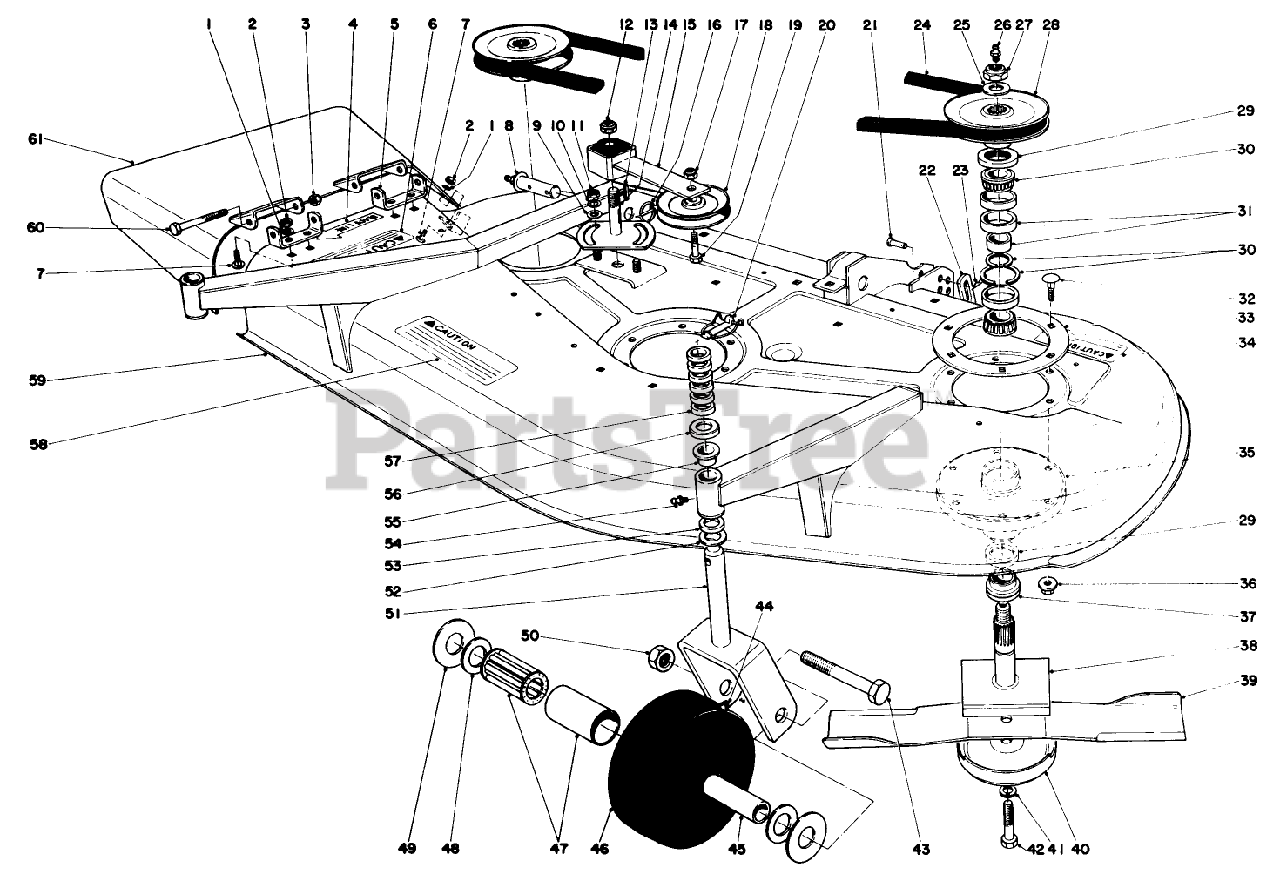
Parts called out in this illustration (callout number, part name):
1	WASHER-LOCK
2	NUT-HEX
3	NUT-LOCK, NI
4	DECAL - BLADE LINE
5	Pivot Bracket Deflector
6	DECAL-CAUTION, DEFLECTOR
7	SCREW-CARR
8	PIVOT PIN WA RO
9	WASHER-FLAT
10	WASHER-LOCK
11	NUT-JAM
12	NUT-LOCK, NI
13	KEY-SQUARE
14	Plate-Idler
15	IDLER ARM ASM
16	PIN-LYNCH
17	NUT-HEX
18	Idler Pulley
19	SCREW-HH
20	PIN-LYNCH
21	PIN-CLEVIS
22	LIFT BRKT LINKAGE R
23	PIN-HAIR
24	V-BELT
25	WASHER
26	FITTING-GREASE
27	NUT-LOCK, NI
28	PULLEY AND HUB ASM
29	SEAL-OIL
30	BEARING ASM
31	SPACER-SET, MATCHED
32	SCREW-CARR
33	SUPPORT-DECK, RING
34	DECAL-CAUTION, BLADE
35	Housing-Spindle
36	NUT-HF
37	SPACER
38	SHAFT
39	Blade
40	Cup-Scalp
41	WASHER-LOCK
42	SCREW-HH
43	SCREW-HH
44	GREASE FITTING
45	SPANNER BUSHING
46	WHEEL
47	ROLLER BEARING
48	BEARING RETAINER
49	THRUST WASHER
50	NUT-LOCK
51	Castor Fork
52	WASHER-THRUST
53	SPACER
54	FITTING-GREASE
55	1-1/8IDX1LG FLG BSHG
56	CASTOR SLINGER
57	SPACER 1/2 IN
58	Decal-Caution
59	52 IN DECK WA RO
60	SCREW-HH
61	DEFLECTOR WA R
